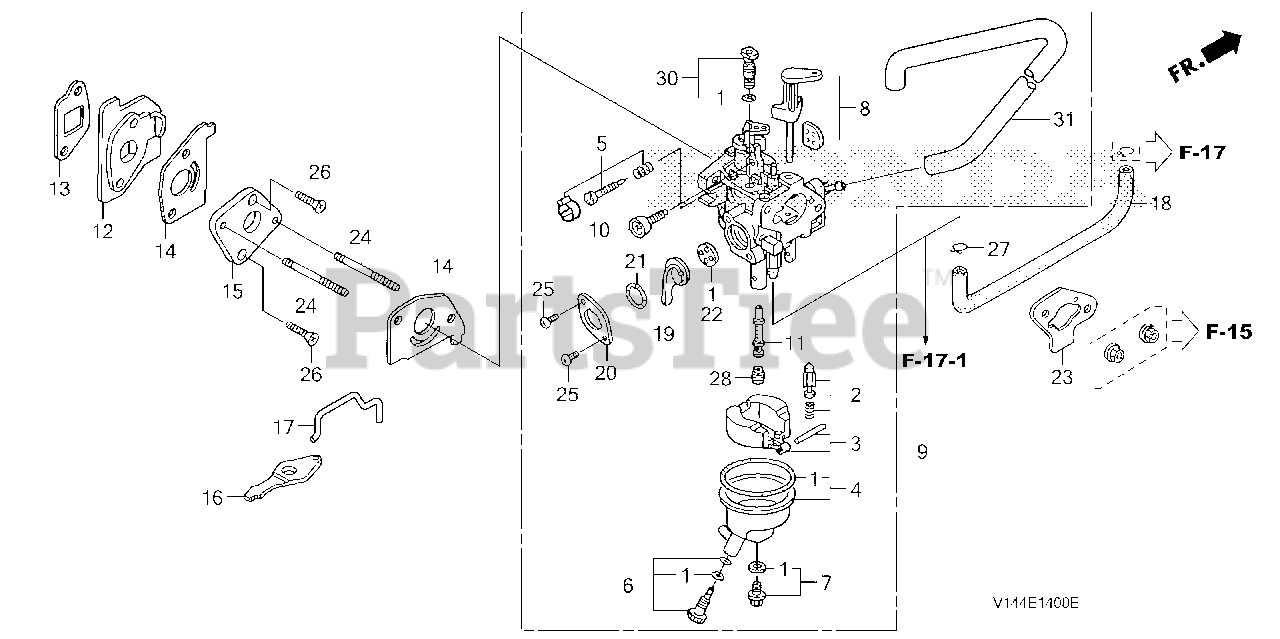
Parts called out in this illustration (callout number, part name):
1	GASKET SET
2	VALVE SET, FLOAT (CARBURETOR NO.) (SEAT NOT INCLUDED)
4	CHAMBER SET, FLOAT
5	SCREW SET
6	SCREW SET, DRAIN (CARBURETOR NO.)
7	SCREW SET (CARBURETOR NO.)
9	CARBURETOR ASSY. (BF24A B)
10	SCREW, THROTTLE STOP
11	NOZZLE, MAIN (CARBURETOR NO.)
12	INSULATOR, CARBURETOR
13	GASKET, INSULATOR (ENGINE NO.)
14	GASKET, CARBURETOR
15	PLATE, CARBURETOR JOINT
18	TUBE A, FUEL
19	LEVER, PETCOCK
20	PLATE, LEVER SETTING
21	SPRING, PETCOCK LEVER (CARBURETOR NO.)
22	GASKET, VALVE
23	GASKET, AIR CLEANER
24	BOLT, STUD (5X81)
25	SCREW, PAN (3X5)
26	SCREW, FLAT (5X20)
27	CLIP, TUBE (B8)
28	JET, MAIN (#45) (CARBURETOR NO.)
28	JET, MAIN (#48) (CARBURETOR NO.)
28	JET, MAIN (#50) Use from Engine SN BF12A B.
30	JET SET, PILOT (#35)
31	BULK HOSE, VINYL (3X6X1000) (3X6X120)
